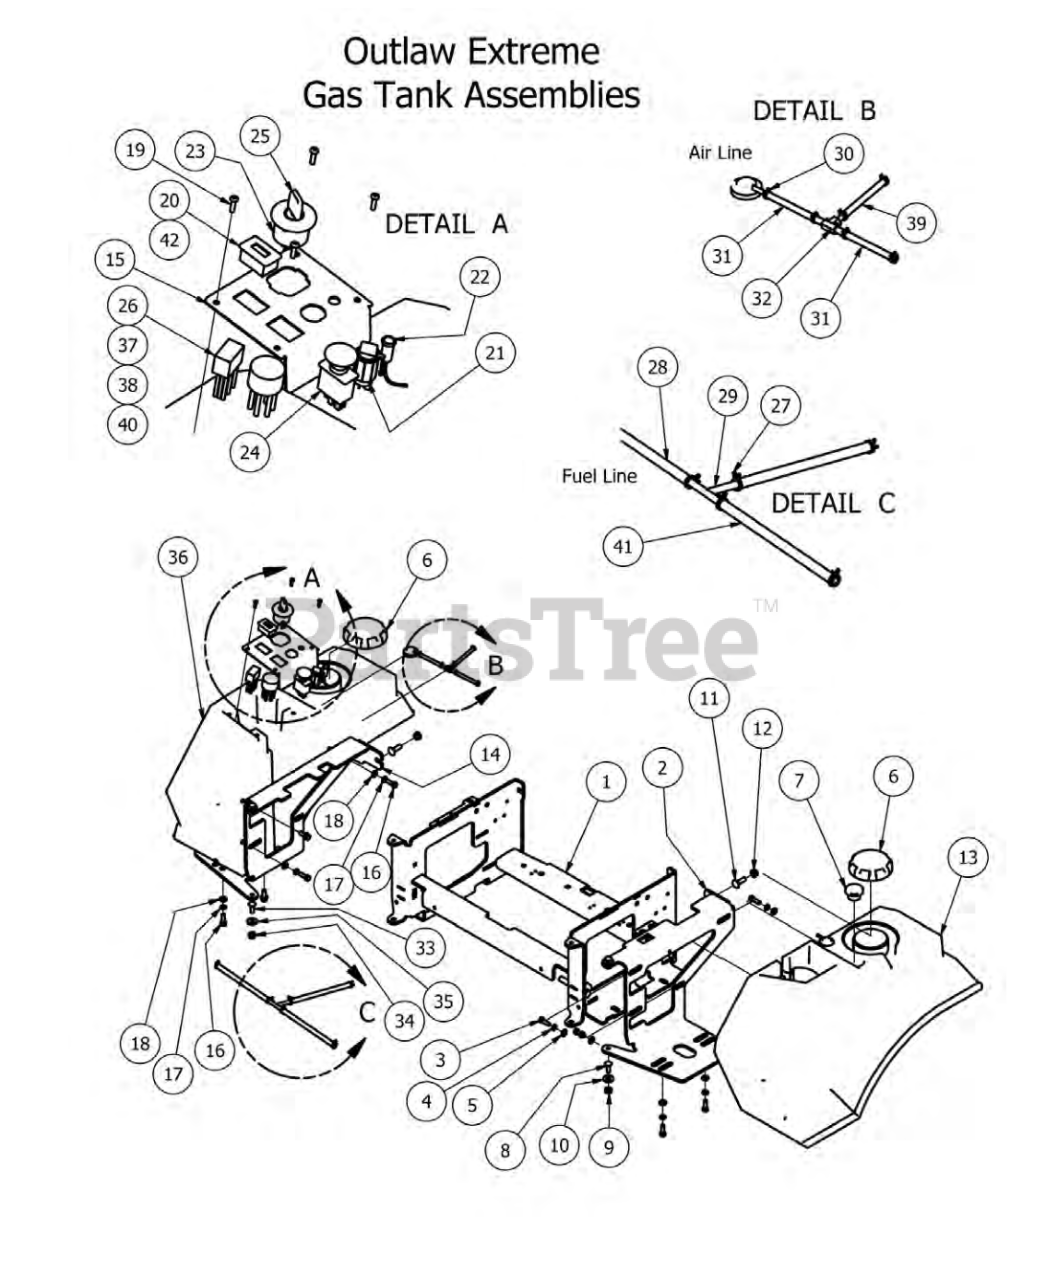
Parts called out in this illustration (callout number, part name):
1	Outlaw Seat Bracket 2012
2	Tank Support 2012 Outlaw (Left)
3	5/16" x 1" Bolt
4	5/16" Lock Washer
5	5/16" Flat Washer
6	3.5" Tethered Fuel Cap
7	Fuel Gauge and Grommet
8	5/16" x 1" Carriage Bolt
9	5/16-18 Nylon Flange Nut
10	360 ID Plastic Washer
11	3/8" x 1 1/4" Carriage Bolt
12	3/8" Nylock Flange Nut
13	2011 CARB Fuel Tank- Extreme- Left
14	Outlaw Tank Support 2012 (Right)
15	Outlaw Instrument Panel 2010
16	5/16" x 1" Bolt
17	5/16" Lock Washer
18	5/16" Flat Washer
19	10-32 x 3/8" Button Socket Head Bolt
20	Tachometer
21	12V AUX Connection
23	Ignition Switch
24	PTO Engager
25	Ignition Key
26	Wiring Harness-36hp Outlaw-Vanguard
27	1/4 fuel clamp
28	1/4" fuel line hose
29	fuel line T
30	3/16 vinyl clamp
31	3/16 Vinyl tubing
32	Brass fuel line T
33	5/16" x 1" Carriage Bolt
34	5/16-18 Nylon Flange Nut
35	.360 ID Plastic Washer
36	2011 CARB Fuel Tank - Extreme - Right
37	Wiring Harness - 31 Kawasaki
38	Wiring Harness - 30 Kohler
39	1/4" Vinyl Tubbing
40	Relay Terminal
41	Fuel line assembly
42	Tachometer-2012 29hp EFI Kohler (only)
